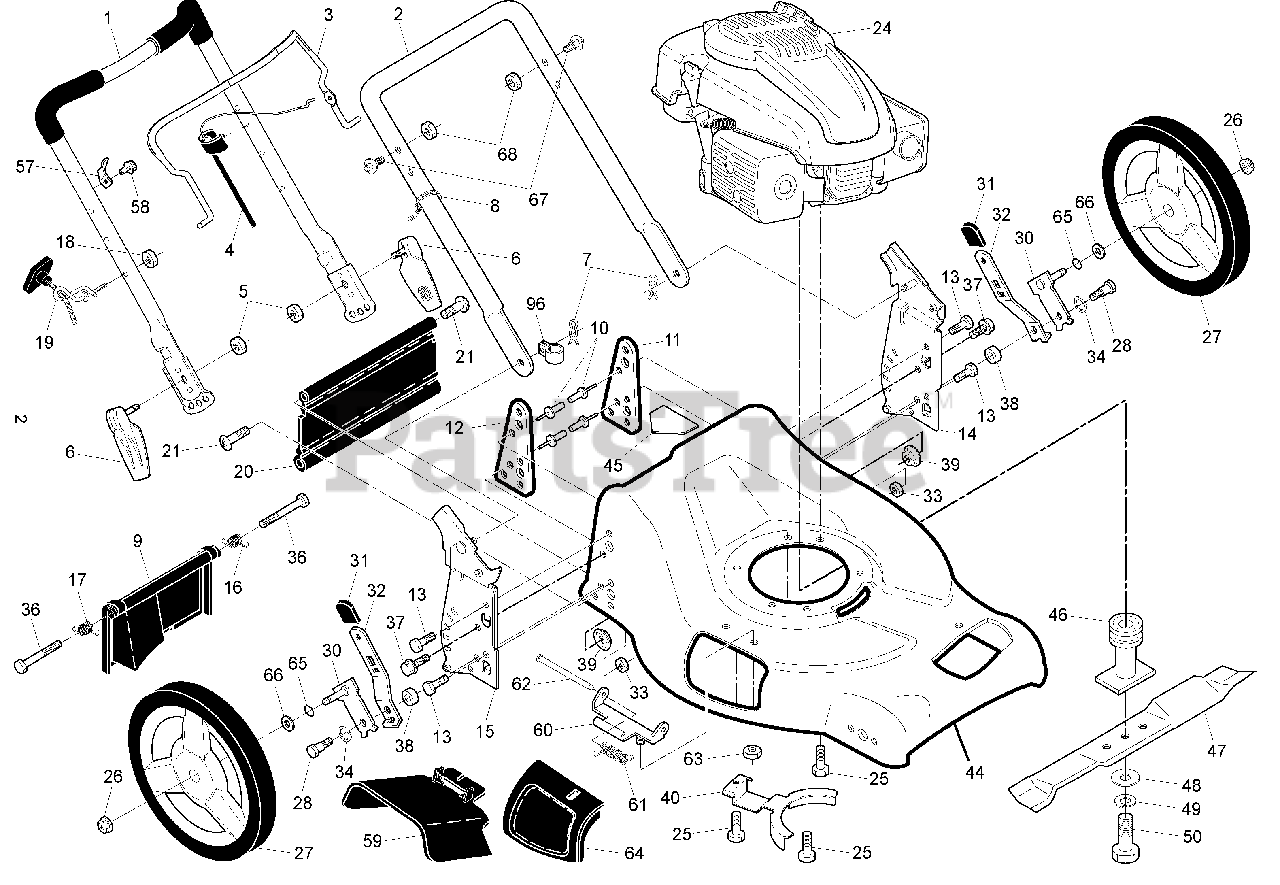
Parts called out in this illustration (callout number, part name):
1	Upper Handle
2	Lower Handle
3	Control Bar
4	Engine Zone Control Cable
5	Locknut, Hex 1/4-20
6	Handle Knob Assembly, Quick-Release
7	Hairpin Cotter
8	Wire Tie
9	Rear Door Assembly
11	Support Bracket, LH
12	Support Bracket, RH
13	Screw 1/4-20 x 5/8
14	Handle Bracket Assembly, LH
15	Handle Bracket Assembly, RH
16	Spring, Rear Door, LH
17	Spring, Rear Door, RH
18	Locknut, Hex 1/4-20
19	Rope Guide
20	Rear Skirt
21	Screw, Hinge
25	Hex Head Thread Rolling Screw 3/8-16 x 1-1/8
26	Hex Flange Nut
27	Wheel & Tire Assembly, Rear, 12"
28	Shoulder Bolt 5/16-18 x .33
30	Axle Arm Assembly, Rear
31	Selector Knob
32	Selector Spring
33	Nut, Hex 5/16-18
34	Washer, Curved, Cylindrical
37	Thread Cutting Screw w/Sems 5/16-18 x 3/4
39	Nut, Hex, Flanged 5/16-18
40	Belt Keeper
44	Lawn Mower Housing
45	Danger Decal
46	Blade Adapter / Pulley
47	Blade 21"
48	Hardened Washer
49	Helical Washer 3/8-24 x 1-3/8 Grade 8
50	Hex Head Machine Screw 3/8-24 x 1-3/8 Grade 8
57	Upstop Bracket
59	Discharge Deflector
60	Hinge Bracket Assembly
61	Spring, Hinge
62	Rod, Hinge
63	Locknut, Hex 1/4-20
64	Mulcher Door
66	Washer, Flat
68	Nut, Hex
96	Clip, Cable
